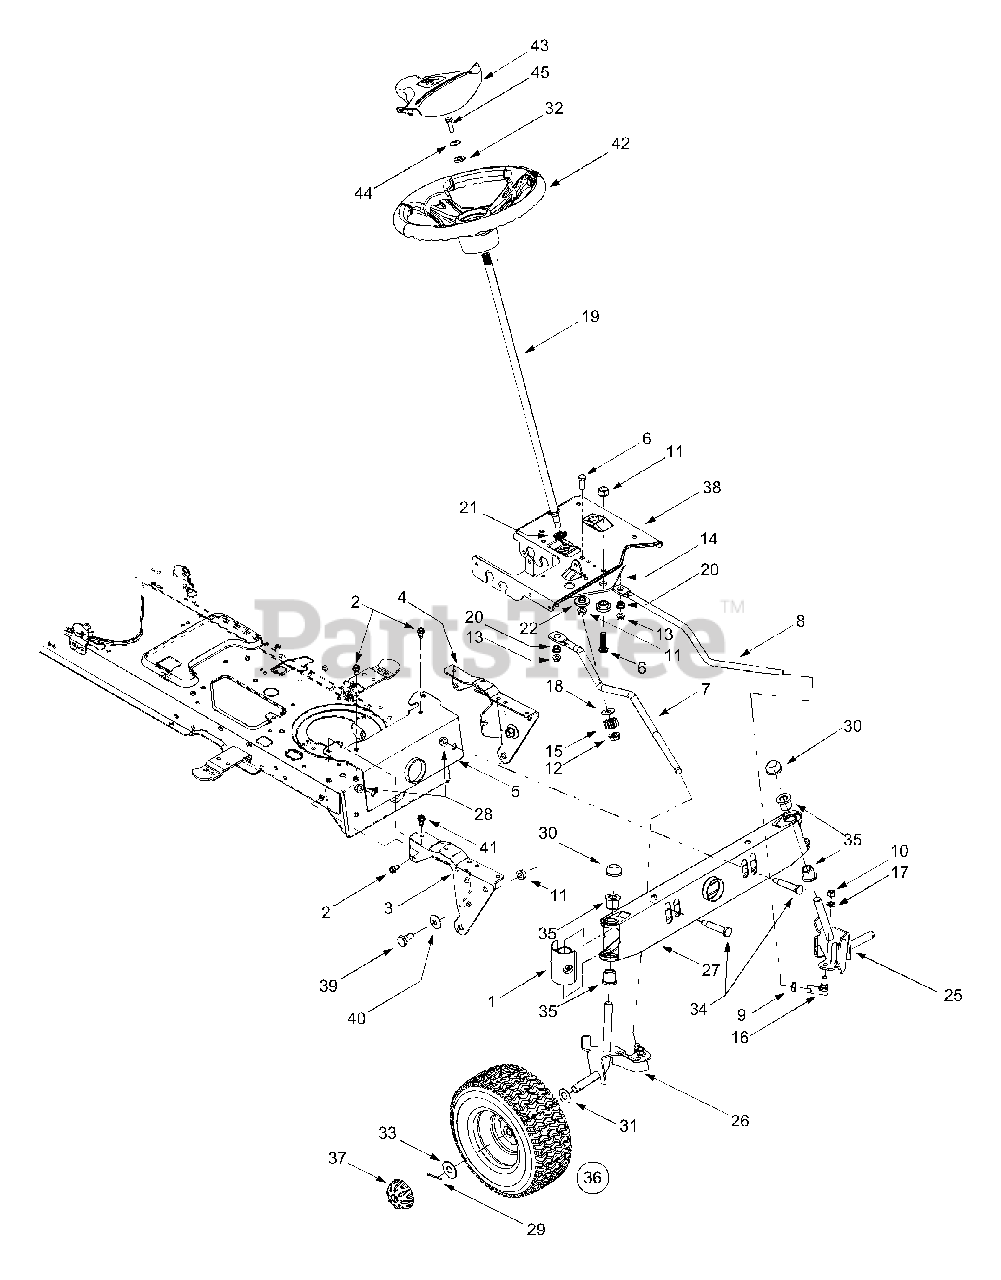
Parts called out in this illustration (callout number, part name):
1	Pivot Bar End Cap w/ Fitting
2	Self-tapping Screw, 16-18 x .625
6	Hex Cap Screw, 3/8-16 x 1.25 (Grade 5)
7	RH Drag Link
9	Jam Nut, 7/16-20 (Grade 2)
10	Hex Nut, 3/8-24 (Grade 2)
11	Flange Lock Nut, 3/8-16
12	Flange Lock Nut, 7/16-20
13	Flange Lock Nut, 5/16-18
14	Steering Gear, 11/90 Ratio
15	Steering Pinion Gear
16	Ball Joint, 7/16-20
17	Lock Washer, 3/8
18	Flat Washer, .51 x 1.12 x .06
19	Steering Shaft, .625 OD x 24.4
20	Plastic Bushing, .38 ID
21	Hex Flange Bearing, 5/8
22	Shoulder Spacer, .38 ID
23	Standard Steering Wheel, 13.25
24	Steering Wheel Cap, Round
25	LH Axle Assembly, .625 Diameter
26	RH Axle Assembly, .625 Diameter
28	Flange Lock Nut, 3/8-16
30	Push Cap, .625
31	Flat Washer, .64 x 1.0 x .12
32	Flat Washer, .406 x .875 x .105
33	Flat Washer, .635 x 1.589 x .06
34	Shoulder Screw, .5 x 2.2, 3/8-16
35	Flange Bearing, .632 ID x .937 OD
37	Deluxe Hub Cap
39	Shoulder Screw, 3/8-16
40	Bell Washer, .39 x 1.13 x .062
41	Self-tapping Screw, 5/16-18 x .75
42	Steering Wheel, Soft Grip, Three Spoke
43	Steering Wheel Cap, Round
44	Bell Washer, .34 x .872
45	Hex Bolt, 5/16-18 X 1
